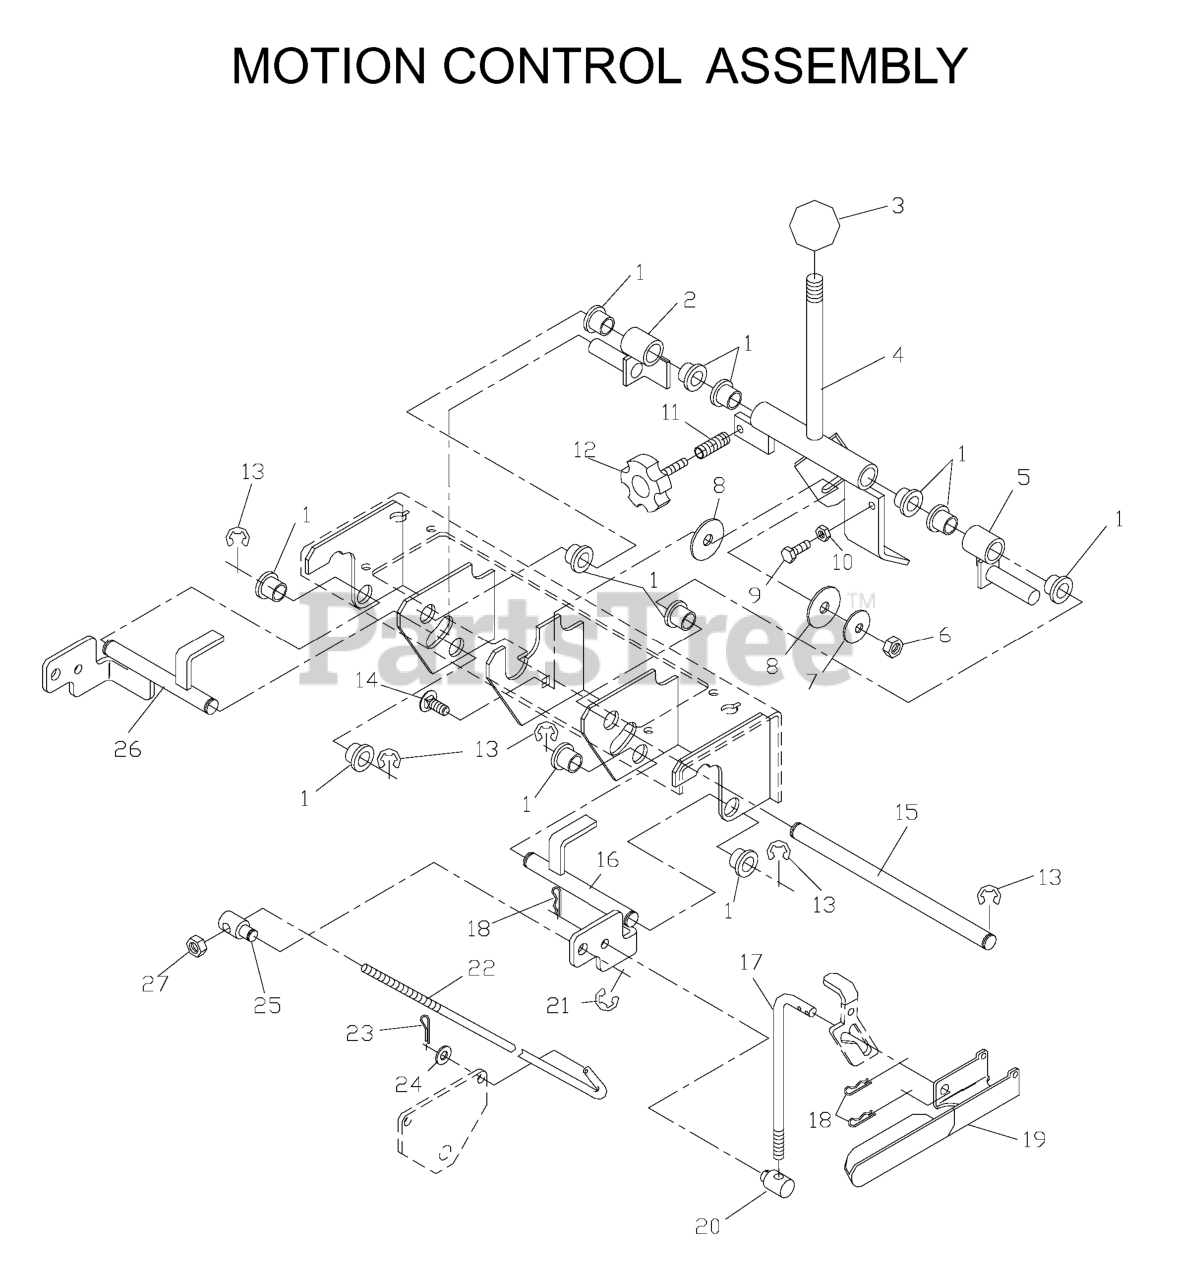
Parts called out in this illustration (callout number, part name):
1	BUSHING, FLANGED NYLON
2	TRACK WELDMENT
4	TRAVEL LEVER
5	TRACK WELDMENT, RT
6	NUT 5/16C CENTERLOCK
7	CONE WASHER
8	WASHER, FRICTION
9	HCS 5/16C X 1
10	NUT 5/16C WHIZ
12	ADJUSTMENT KNOB
13	E-RING 1/2 (2 2)
14	RHSNB 5/16C X 1
15	TRAVEL BAR
16	CONTROL WELDMENT, RT
17	CONTROL LINK
18	HAIRPIN #2
19	CONTROL LEVER RT
20	SWIVEL (SHORT)
21	E RING 3/8"
23	COTTER PIN 3/32 X 3/4
24	WASHER 5/16 FLAT
26	CONTROL WLDMT, LT
27	NUT 5/16 NYLOC
